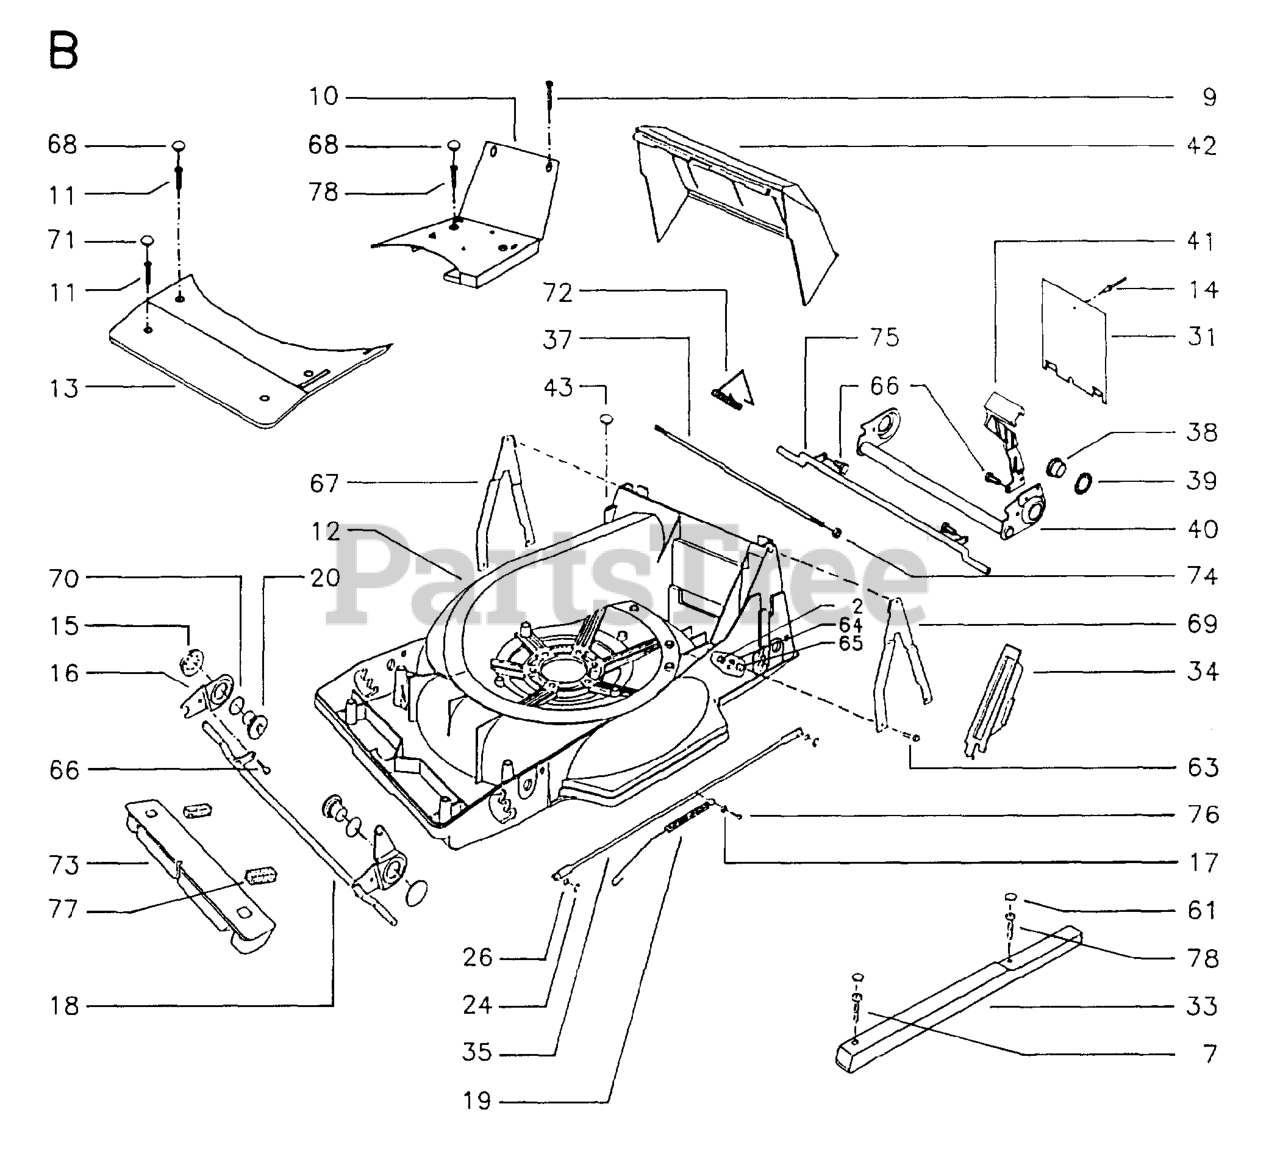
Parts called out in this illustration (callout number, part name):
2	LOCKNUT M8
10	BRACKET 48S
31	REPL BY 516 47 87-00
34	HEIGHT ADJ. COVER
37	REPL BY 516 49 96-01
39	LOCK WASHER
76	SCREW TAPTITE
